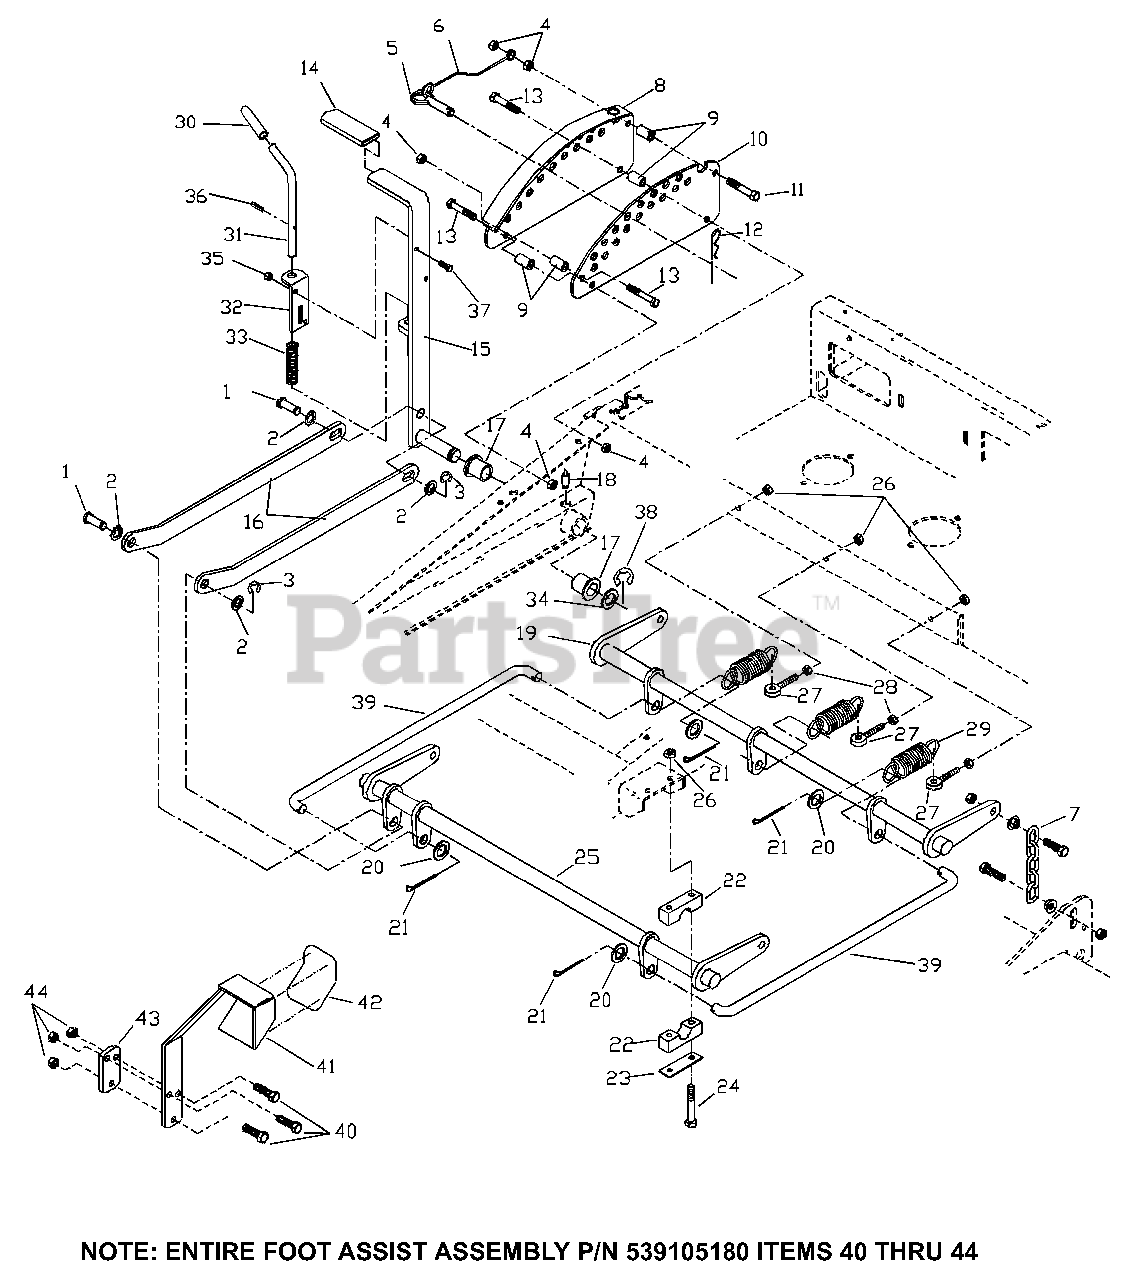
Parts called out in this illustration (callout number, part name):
1	CLEVIS PIN
2	MACH. BUSHING
3	5/8 E - RING
4	NUT 3/8C CTR. LOCK
7	LIFT CHAIN
8	ADJ. PLATE WLDMT.
9	DECK LIFT SPACER
10	ADJ. PLATE PAINTED
11	HCS 3/8C X 2.5
12	#4 HAIR PIN
13	HCS 3/8C X 2.25
15	LEVER WLDMT.
16	LIFT LINKAGE
17	FLANGE BUSHING
18	ZERK - LONG
19	LIFT SHAFT
20	5/8 SAE WASHER
21	COTTER PIN
22	PILLOW BLOCK
23	SUPPORT PLATE
24	HCS 5/16C X 2.5
25	LIFT SHAFT, FRONT
26	NUT 5/16C CTR. LOCK
28	5/16C WHIZ NUT
29	DECK LIFT SPRING
32	PIN MT.,UPPER
34	MACH. BUSHING
35	NUT 1/4C CTR. LOCK
36	3/16 X 1 ROLL PIN
37	HCS 1/4C X 3/4
38	7/8 E - RING
39	CONN. LINK
40	HCS 3/8 X 1.5
41	LIFT PEDAL
42	ANTI-SKID PAD
43	TIGHTING PLATE
44	NUT 3/8 NYLOC
539105180	FOOT ASSIST ASSEMBLY
